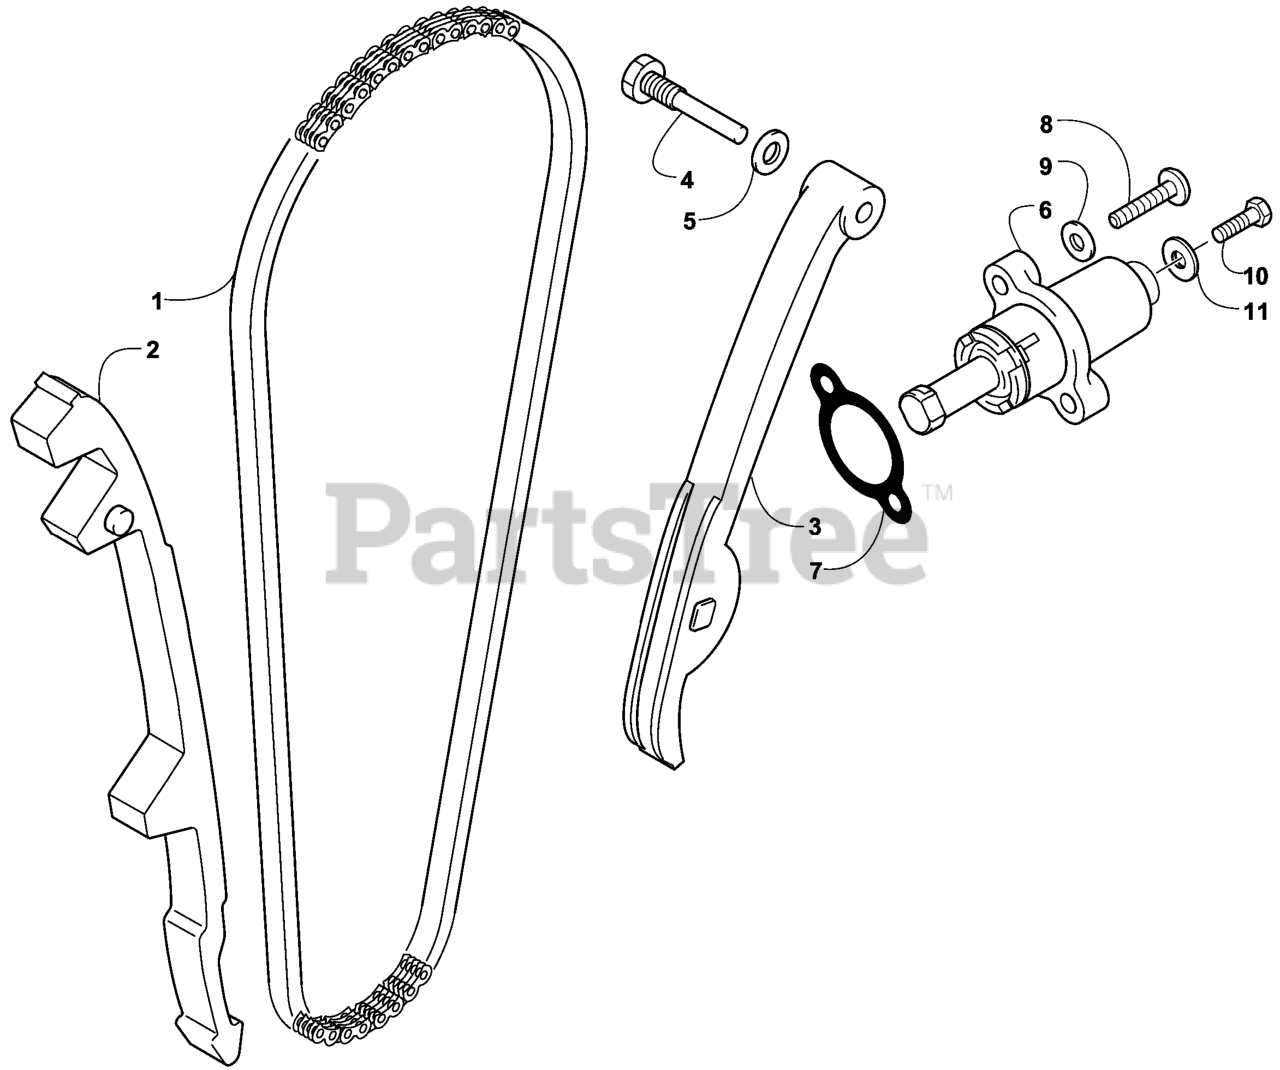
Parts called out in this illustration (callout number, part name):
1	Chain, Cam
2	GUIDE-CHAIN
3	TENSIONER-CHAIN
4	SCREW-HH, SHOULDER
5	WASHER-CRUSH
6	TENSIONER ADJUSTER ASM
8	SCREW-TSPNH
9	SEAL-FASTENER
10	SCREW-HH
11	WASHER-ALUMINUM
